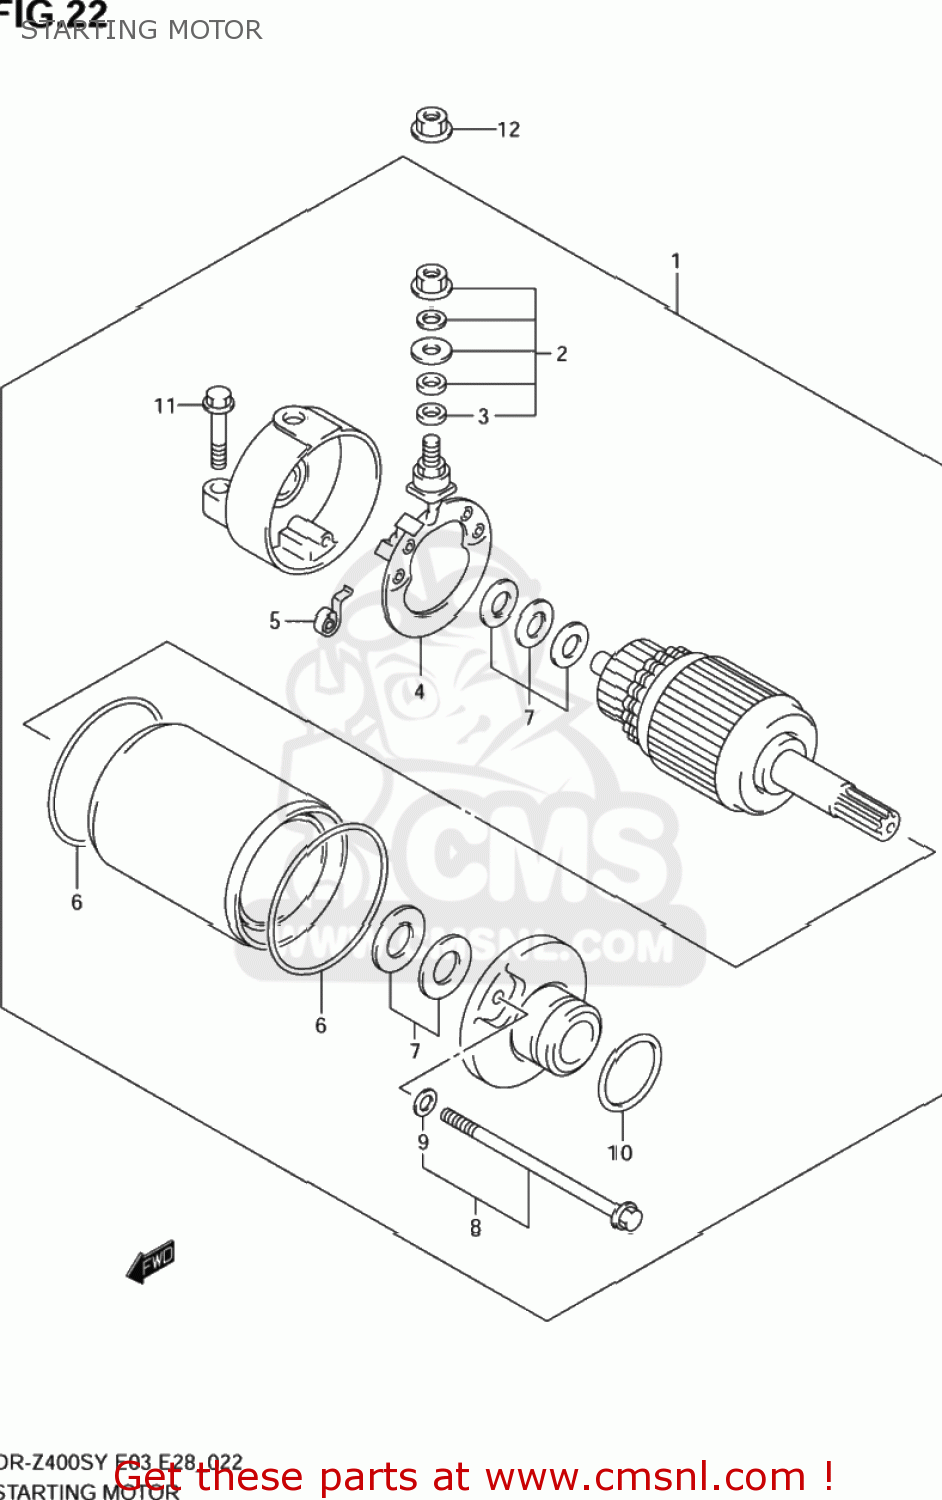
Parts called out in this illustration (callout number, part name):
1	MOTOR ASSY,STARTING
2	BRUSH TERMINAL SET
3	O RING
4	BRUSH HOLDER SET
5	SPRING,BRUSH
6	O RING
7	SHIM SET,STARTING MOTOR
8	BOLT SET
9	O RING
10	O RING(D:3,ID:24.5)
11	SCREW
12	NUT
